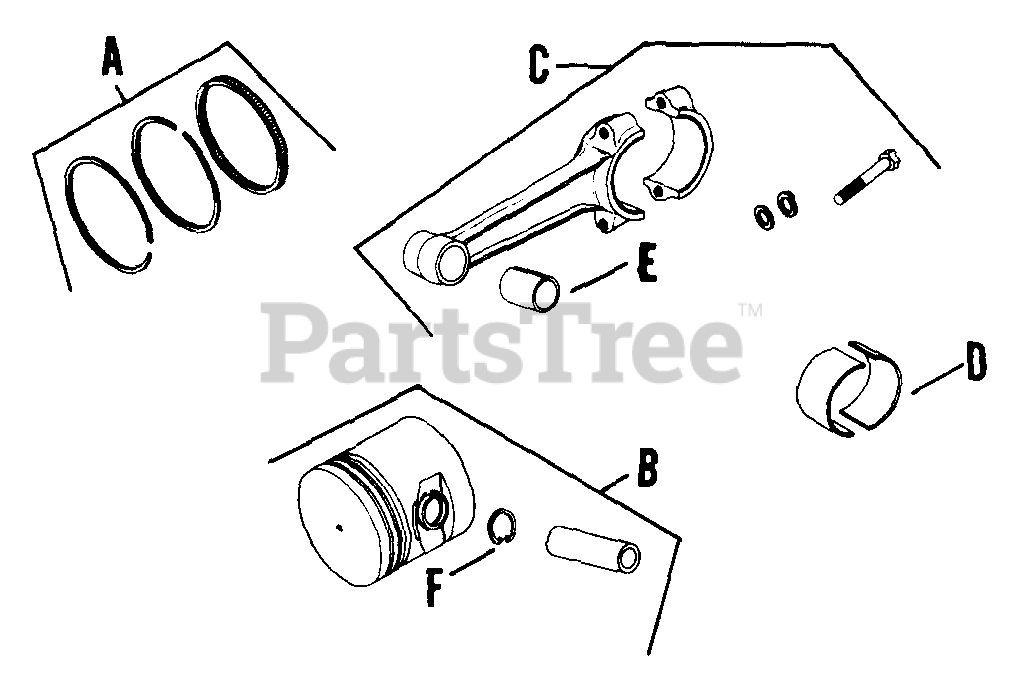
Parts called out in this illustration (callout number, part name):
A	RINGS STD.
A	RINGS .010 - DISCONTINUED
A	RINGS .020 - DISCONTINUED
A	RINGS .030 - DISCONTINUED
B	PISTON - USE 49 874 01
B	PISTON - USE 49 874 03
B	PISTON - USE 49 874 04
B	PISTON - USE 49 874 05
C	ROD STD. - DISCONTINUED
D	BEARING - USE 48 755 06
D	BEARING - USE 48 755 07
D	BEARING - USE 48 755 09
